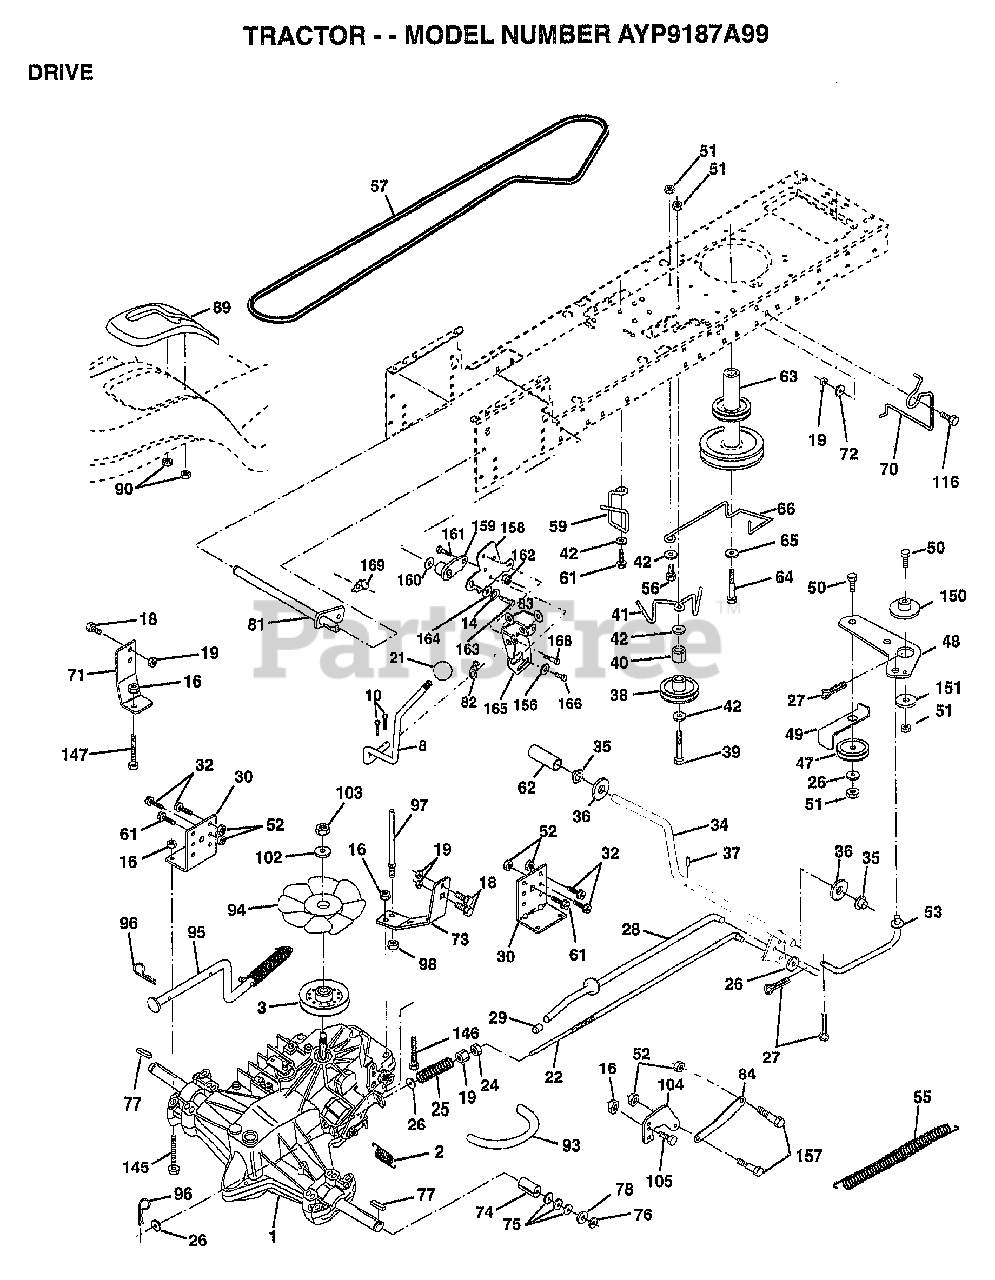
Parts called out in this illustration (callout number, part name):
2	SPRING RET BRAKE
3	PULLEY.TRANSAXLE
8	RODL.SHIFT.FEND.ADJ.STLT
10	PIN COTTER 1/8
14	LOCKWASHER
16	NUT
18	BOLT
19	NUT
21	KNOB T (1/2-HOLE)
22	ROD.BRAKE.HYDRO.
24	NUT
25	SPRING ROD LT
26	WASHER
27	COTTER PIN
28	ROD.BRAKE.PARK.LT
30	TRANSAXLE MTG BKT
32	BOLT
34	SHAFT ASM-PEDAL F
35	NYLON BEARING
36	WASHER LT
38	FLAT IDLER PULLEY
39	BOLT
40	SPACER T
41	"KEEPER,BELT.IDLER FLAT"
42	WASHER
48	BELLCRANK.CLUTCH
49	RETAIN BELT
53	"LINK, CLUTCH T"
55	"SPRING, RETURN LT"
57	"BELT.GD DRV 82"""
59	KEEPER BELT CNTSP
61	SCREW
62	PEDAL COVER T
63	PULLEY.ENGINE
64	BOLT
65	LOCKWASHER
65	BRKT.PIVOT.LEVER
66	KEEPER-BELT
70	KEEPER BELT ENG
71	STRAP TORQ LH HYD
72	WASHER
73	"STRAP-TORQUE,RH"
74	SPACER SPLIT
75	WASHER
76	E-RING LT
77	SQUARE KEY
78	WASHER
81	SHAFT.ASM.CROSS
82	SPRING.SHIFT.STLT.GREY
83	WASHER
84	LINK.TRANSAXLE.LT/YT
89	CONSOLE.SHIFT
90	NUT
93	"LINE FUEL HYD 4"""
94	"FAN 7"" HYDRO"
96	RETAINER M
97	BOLT KEEPER RH
98	NUT
102	WASHER BELLEVILLE
104	ARM CONTROL HYDRO
105	SCREW CAP 5/16-18
116	BOLT RDHD 3/8-16
145	BOLT.HEX.FLGHD
146	BOLT.HEX.FLGHD.
147	BOLT.HEX.FLGHD
150	BUSHING.BELLCRANK.GRD.DR
151	WASHER
156	WASHER.SRRTD.5/16
156	HUB.SHIFT
157	"BOLT,SHOULDER"
158	BRKT.SHIFT.MOUNT
160	WASHER
161	BOLT T
164	WASHER.5/8X.281X10GA
166	SCREW.5/16-18X5/8
168	BOLT.SHOULDER.5/16-18X.561
169	PLATE.FASTENING
